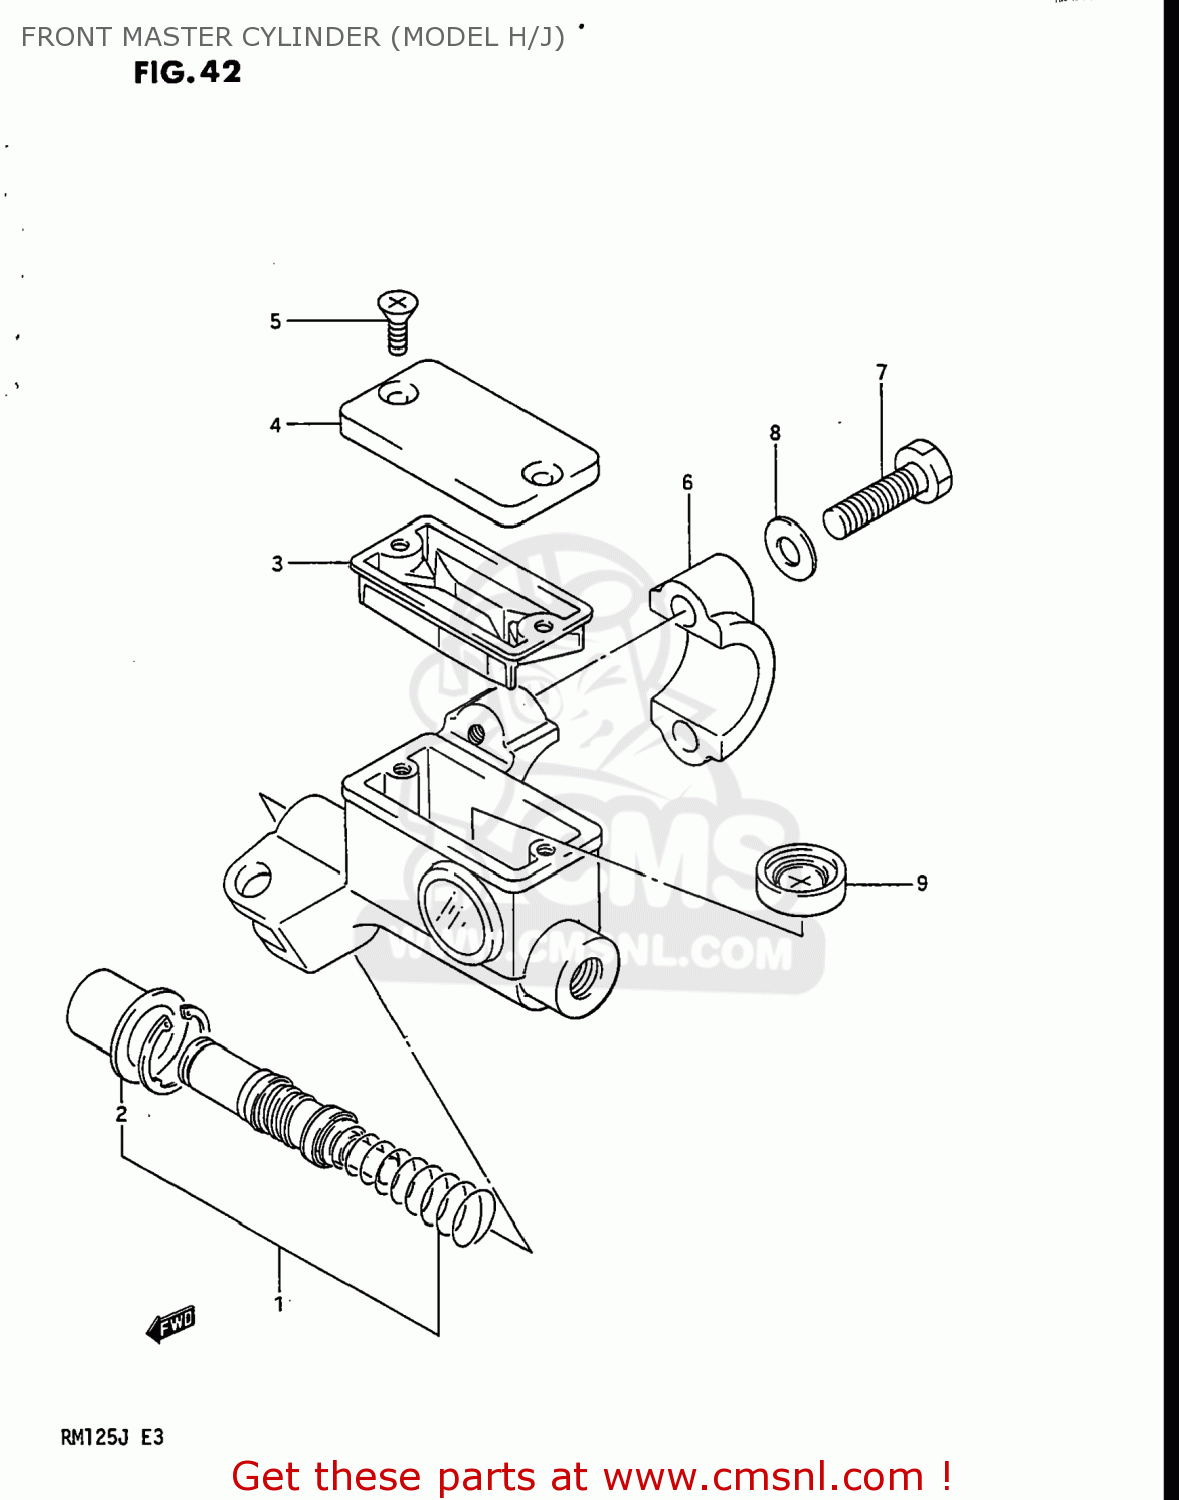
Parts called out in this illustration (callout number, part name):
1	PISTON & CUP SET
2	BOOT
3	DIAPHRAGM
4	CAP
5	SCREW
6	HOLDER,MASTER CYLINDER
7	BOLT
8	WASHER
9	SEPARATOR
